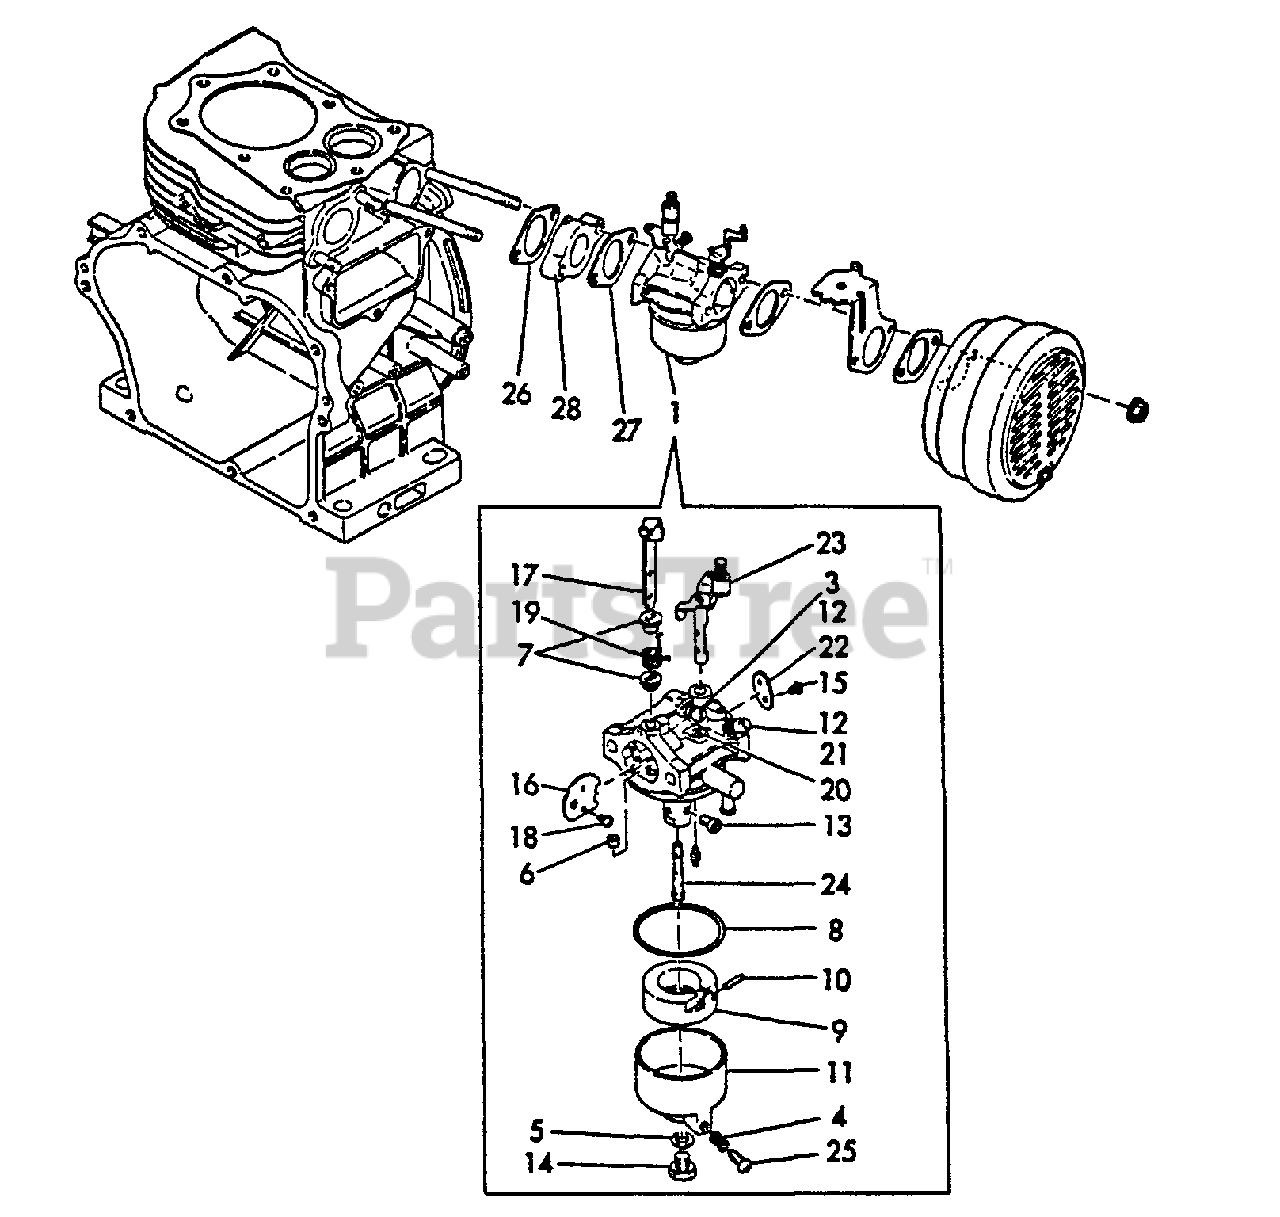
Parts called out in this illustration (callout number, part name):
1	CARBURETOR
3	SCREW, THROTTLE
6	RING, CHOKE SHAFT
7	RING, CHOKE LEVER
8	GASKET, FLOAT CHAMBER
9	FLOAT
10	PIN
11	BODY
12	SPRING
13	JET, MAIN
14	BOLT
15	SCREW
16	VALVE, CHOKE
17	LEVER, CHOKE
19	SPRING, CHOKE
20	JET, PILOT
21	SCREW, PILOT
22	VALVE, THROTTLE
23	SHAFT, THROTTLE
24	NOZZLE, MAIN
25	SCREW
26	GASKET, SPACER
27	GASKET, INTAKE
28	GASKET, INTAKE
